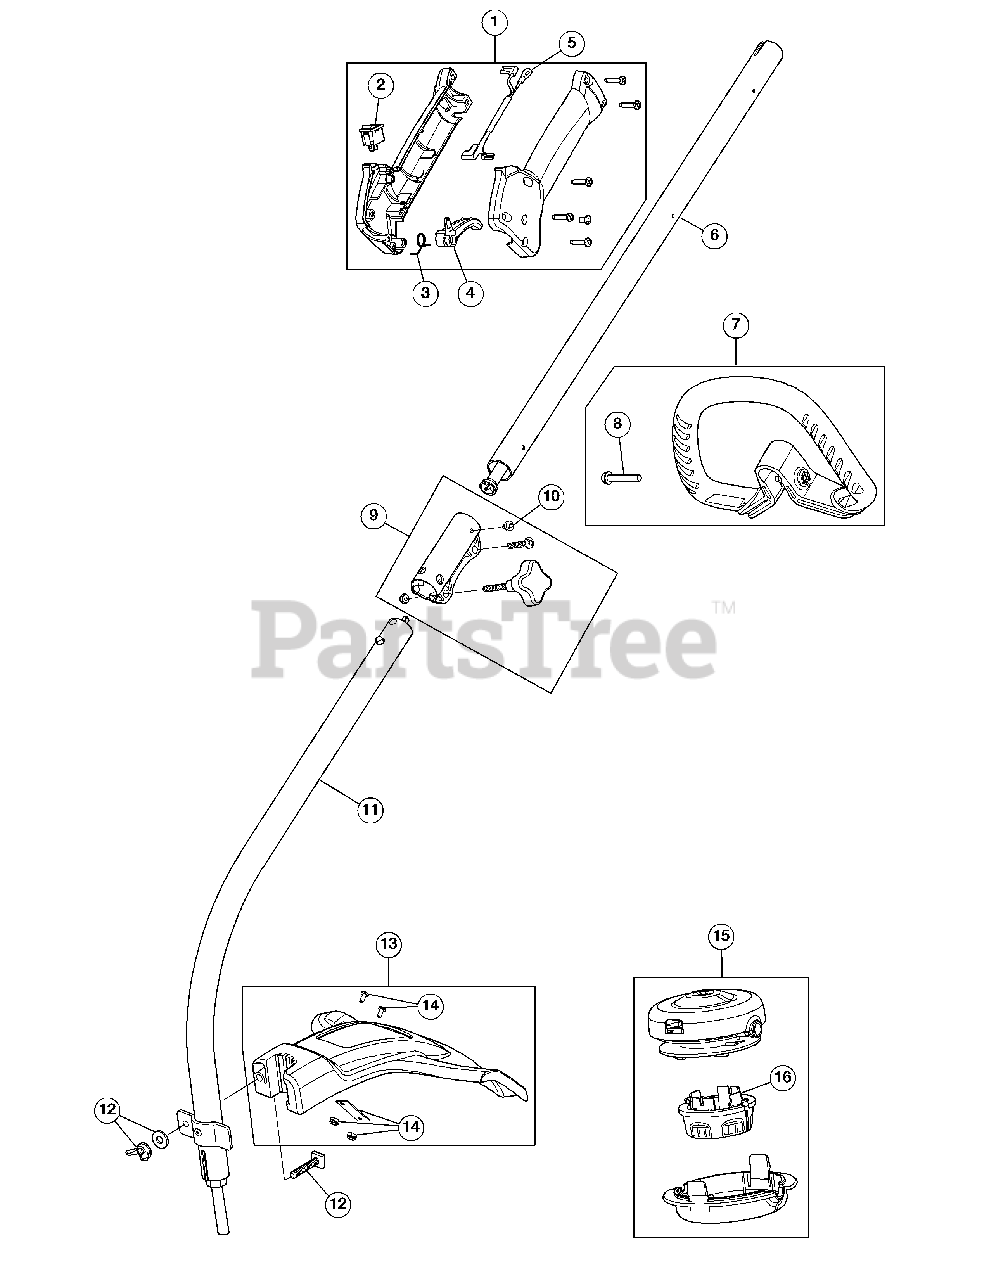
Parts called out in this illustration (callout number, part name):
1	Throttle Housing Assembly (Incl. 2 - 4)
2	Switch Assembly
3	Throttle Trigger Spring
4	Throttle Trigger
5	Throttle Cable Assembly
6	Upper Drive Shaft Housing Assembly
7	D-Handle Assembly (Incl. 8)
9	Split Boom Coupler (Incl. 10)
10	Coupler Anti-Rotation Screw
11	Lower Drive Shaft Housing Assembly
12	Shield Mounting Hardware
13	Shield Assembly (Incl. 14)
14	Blade Assembly
15	Cutting Head Assembly (Incl. 16)
